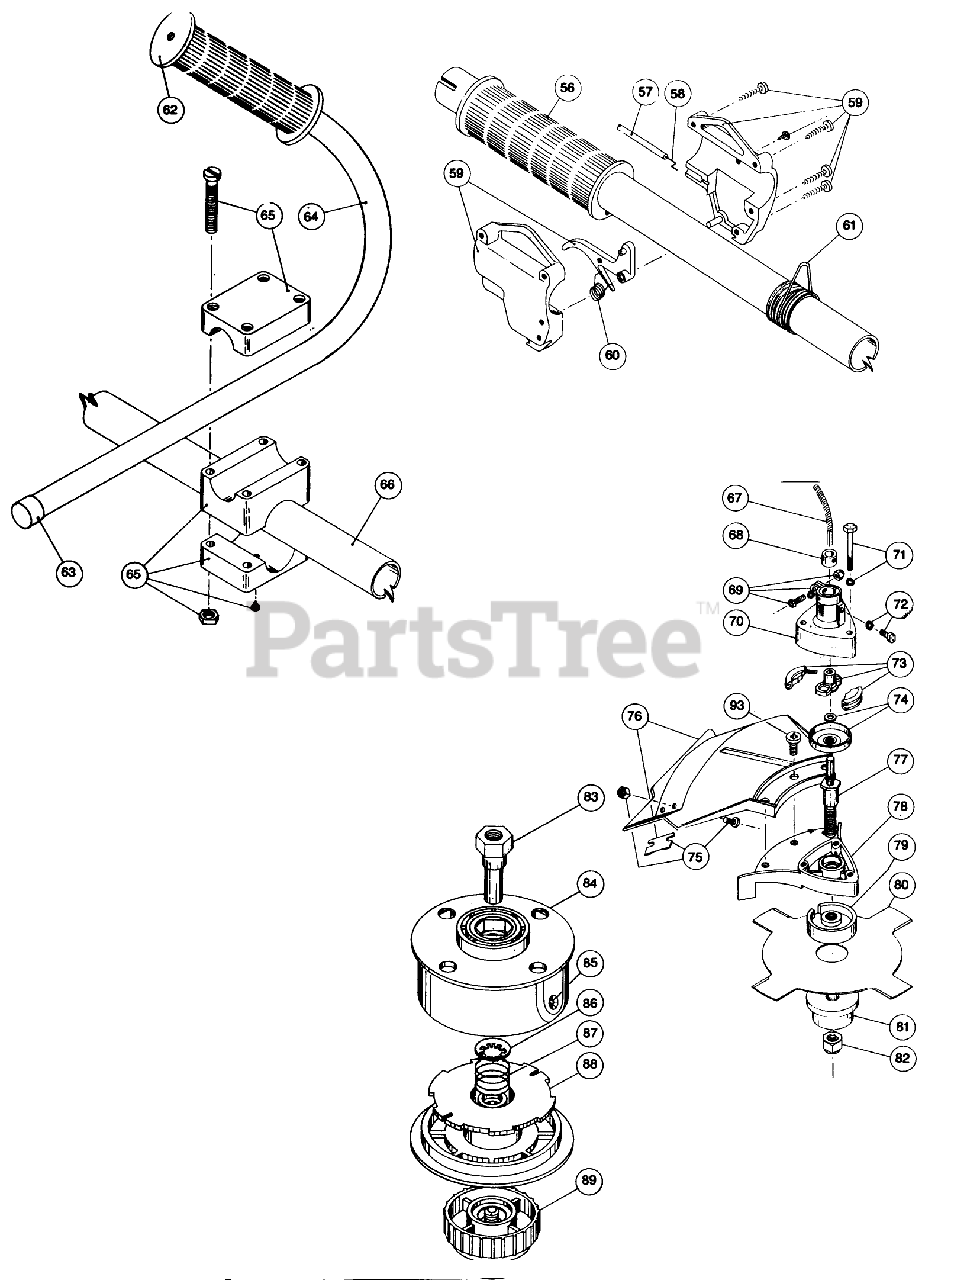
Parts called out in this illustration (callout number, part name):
57	THROTTLE CABLE HSG
58	THROTTLE CABLE WIRE
60	THROTTLE TRIGGER SPRING
63	TUBE CLOSURE
65	HANDLE BRACKET ASM
75	BLADE ASM
76	GUARD & BLADE ASM
83	SPOOL SHAFT
84	OUTER SPOOL EYELET ASM
86	RETAINER
93	GUARD MNTG SCREW ASM
